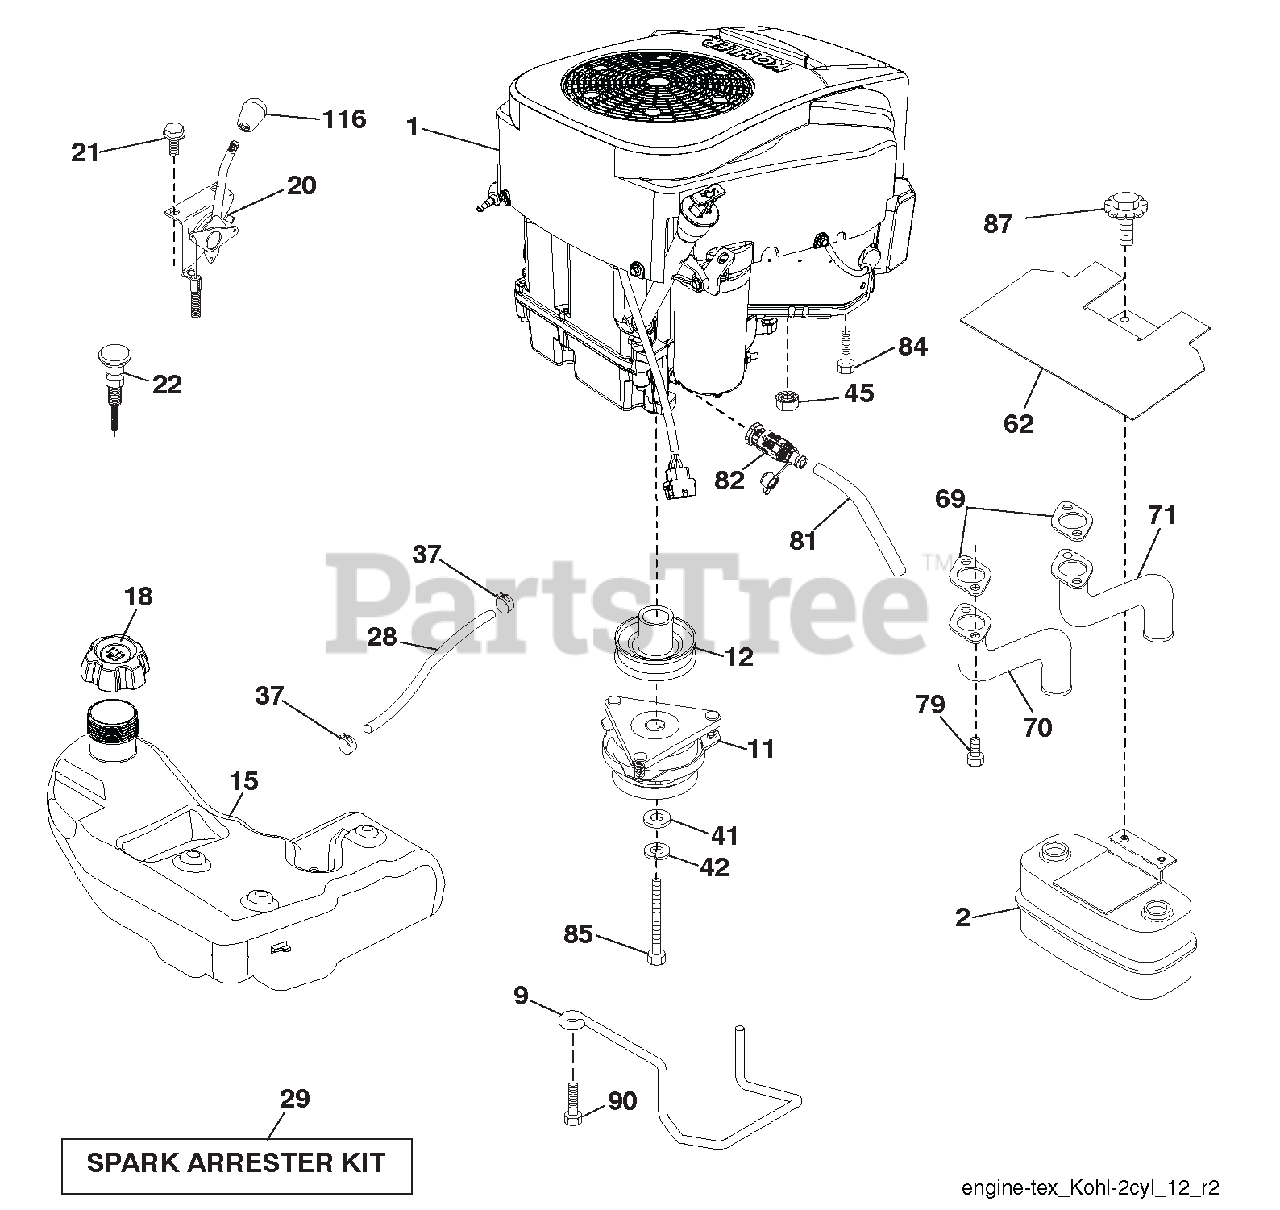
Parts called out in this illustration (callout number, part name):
2	MUFFLER ASM.TWIN.LO-TONE
9	KEEPER.BELT.ENGINE.4.25"
11	CLUTCH ELECTRIC
12	PULLEY.ENGINE
15	TANK.FUEL
18	CAP FUEL
20	CONTROL.THROTTLE
22	CONTROL CHOKE
28	LINE.FUEL.64"REAR.EMIS.CA.LP
29	KIT.SPARK ARRESTOR(392390 B&S)
37	CLAMP.HOSE.BLK.
41	WASHER.1-1/2 ODX15/32 IDX.250
42	WASHER.LOCK.HVY HLCL.SPR.7/16
45	Nut, Keps Hex 1/4-20 unc
62	SHIELD.HEAT.MUFFLER.
70	PIPE.EXHAUST.LH.CV18/20
71	PIPE.EXHAUST.RH.CV18/20
79	SCREW.SOCKET HD.5/16-18 X .75
81	TUBE.DRAIN.OIL.EASY
82	VALVE OIL DRAIN
84	SCREW.3/8-16 X 1.SMGML.TAP/R
85	BOLT HEX 7/16-20 X 3.5 GR.5
87	BOLT.5/16-18UNCX3/4 W/SEMS.BLK
90	SCREW.3/8-16X1.SMGML.TAP/R.BLK
116	KNOB SHIFT
